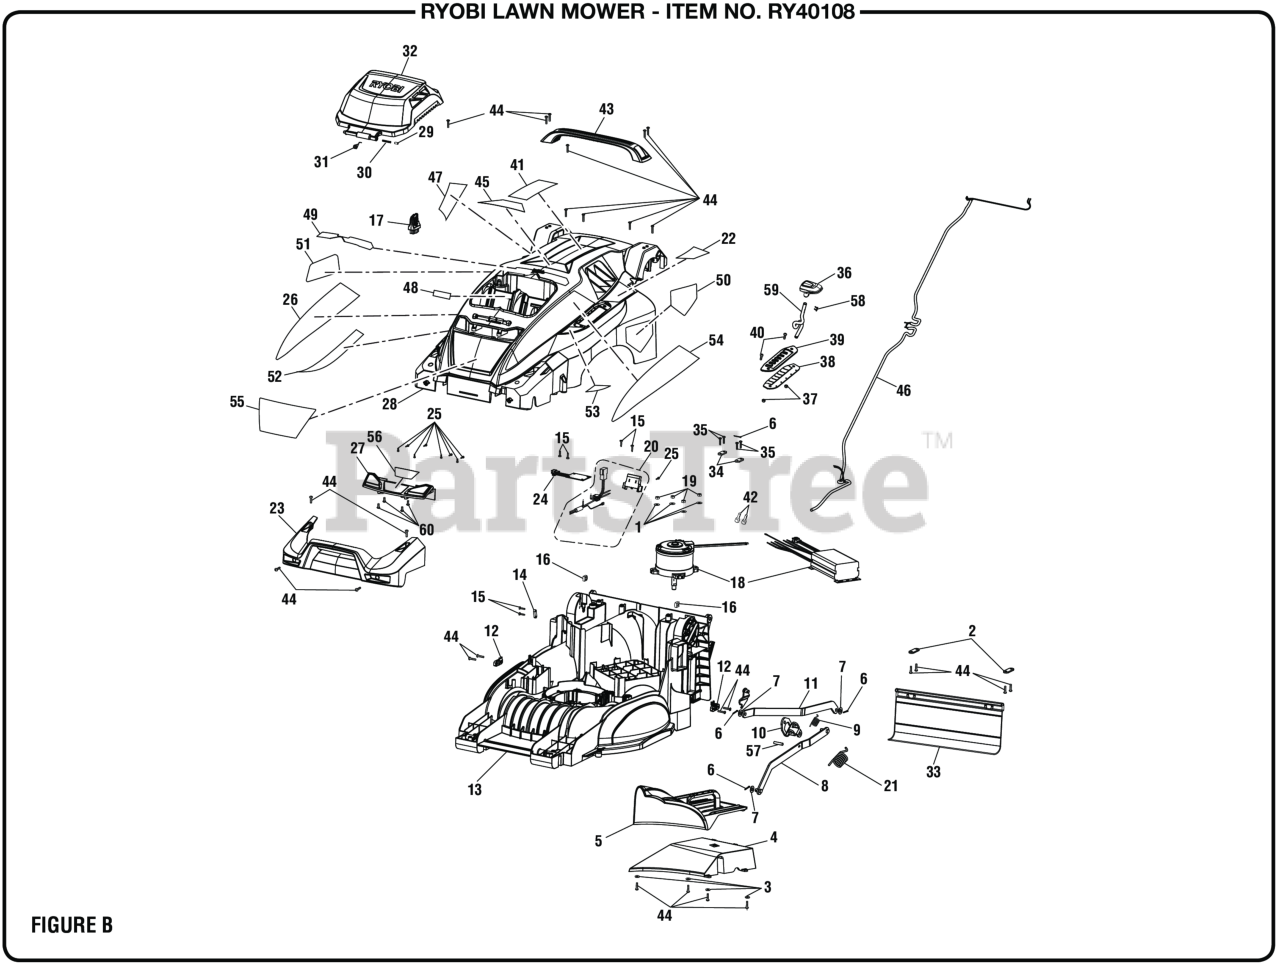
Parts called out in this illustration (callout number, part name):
1	Washer (ID6.2 x OD15 x 0.08t)
2	Axle Pressure Plate
3	Washer (ID4.5 x OD10 x 1t)
5	Mulching Plug
6	Cotter PinÏ? (2.5)
7	Washer (ID8.4 x OD18 x 1t)
8	Front Lift Rod
9	Torsion Spring (Height Adjustment)
10	Height Adjustment Bracket
11	Rear Lift Rod
12	Axle Mount
13	Deck
14	Wire Press Plate
15	Screw (M4 x 16 mm, T20 Torx Pan Hd.).
16	Square Nut (M8)
17	Start Key
18	Motor and Controller Assembly
19	Lock Nut (M6)
20	Key Holder Assembly
21	Rentention Spring
22	Height Adjustment Label
23	Front Bumper
24	Circuit Board (EU17171, & After A.D.C. Week 17, 2017 Light Assembly)
25	Screw (M3 x 8 mm, Pan Hd., Pan Hd)
26	Brushless Label (Right)
27	Light Assembly w/Label
28	Deck Cover
29	Battery Door Axle
30	Compression Spring
31	Battery Cover Spring
32	Battery Cover
34	Pressure Plate (Height Adjustment)
35	Screw (M4 x 18 mm, T20 Torx Pan Hd.)
36	Height Adjustment Handle
37	Lock Nut (M5 x 0.8 mm)
38	Shifter Boot
39	Height Adjustment Plate
40	SCREW (M5 x 16 mm SOC. WASHER HD. CAP)
41	Bilingual Danger (French/Spanish) & Trilingual Warning (English/French/Spanish) Label
42	Terminal Block w/Screw
43	Carrying Handle
44	Screw (M4 x 20 mm, T20 Torx Pan Hd. S.T.)
45	Danger/Warning Icon Label (English)
46	Wiring Harness (EU17301 & After, A.D.C. Week 30, 2017)
47	40V Lithium Label
48	On Board Battery Storage Label
49	Start Key Label
50	Danger Label (No Hands/Feet)
51	Data Label
52	RYOBI Label (Right)
53	Logo Label
54	Brushless Label (Left)
55	40V Brushless Logo Label
56	LED Headlight Label
57	Axle (Height Adjustment)
58	Screw (M3 x 9 mm, Flat Hd.)
59	Lever Arm
60	Screw (M4 x 10 mm, T20 Torx Pan Hd.)
